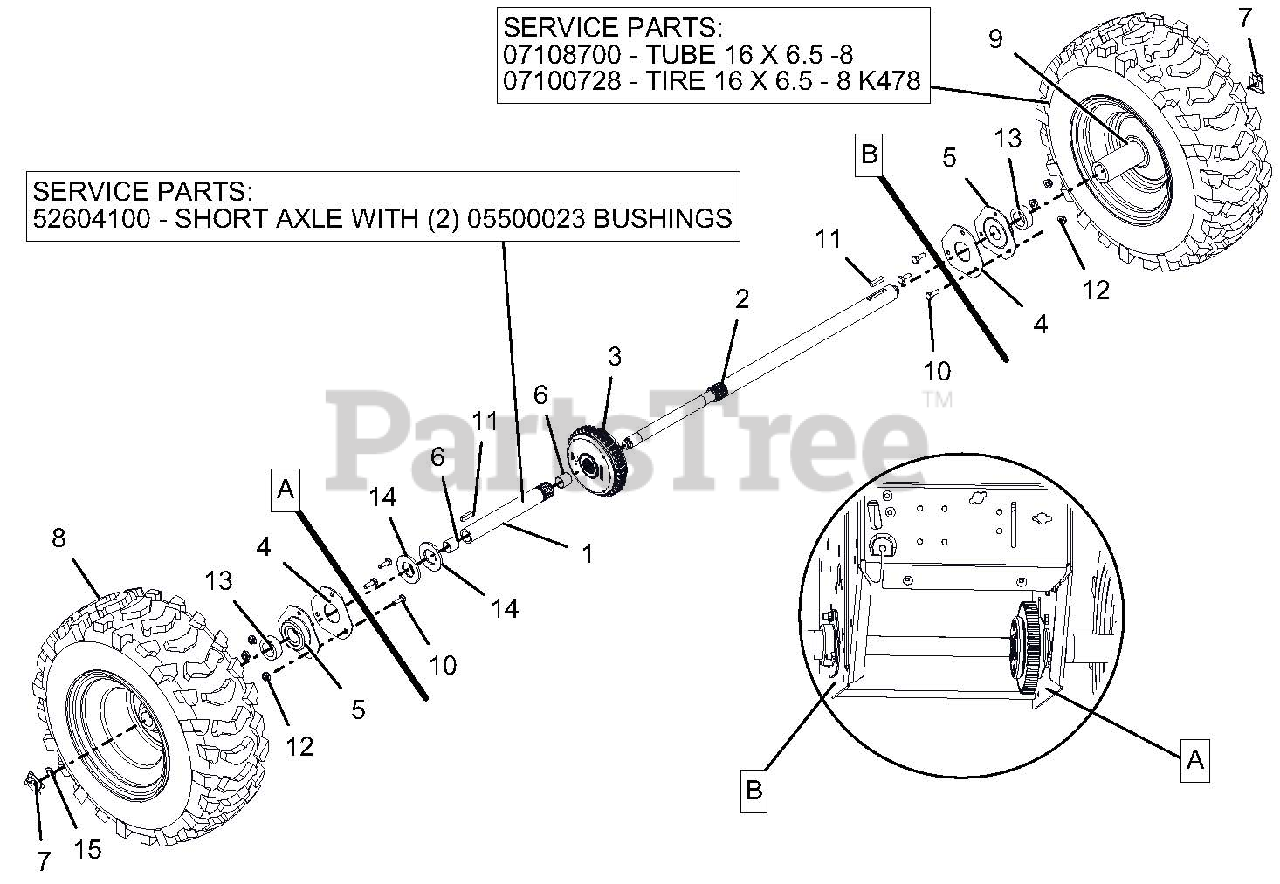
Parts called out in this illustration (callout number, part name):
1	AXLE, SHORT-PRO AUTO DIFF
1	AXLE, SHORT-AUTO W/BUSHINGS
1	BSHG-SLV .706X.764X.75 BRZ
2	AXLE, LONG-PRO AUTO DIFF
3	DIFFERENTIAL, AUTOMATIC
4	PLATE, BEARING SPACER
5	BRG-FLG 1.003/1.000 3 BOLT
6	BSHG-SLV .706X.764X.75 BRZ
7	CLIP, SNAP .625 DIA
8	TIRE/WHEEL, RH 16X6.50-8 DIFF
9	TIRE/WHEEL, LH 16X6.50-8 DIFF
9	TUBE
9	TIRE, 16X6.50-8 K478
10	@BLT-HEX .25-20X.75 GR5 YWZC
11	KEY-RECT .25X.188X1.00
12	@NUT-LK-CTR-FLG .25-20 YWZC
13	SPACER, PRO AXLE BEARING
14	WSHR-FL-STL- 1.062X2.0X.134 YZ
15	RG-RTNG-EXT .625X.042
